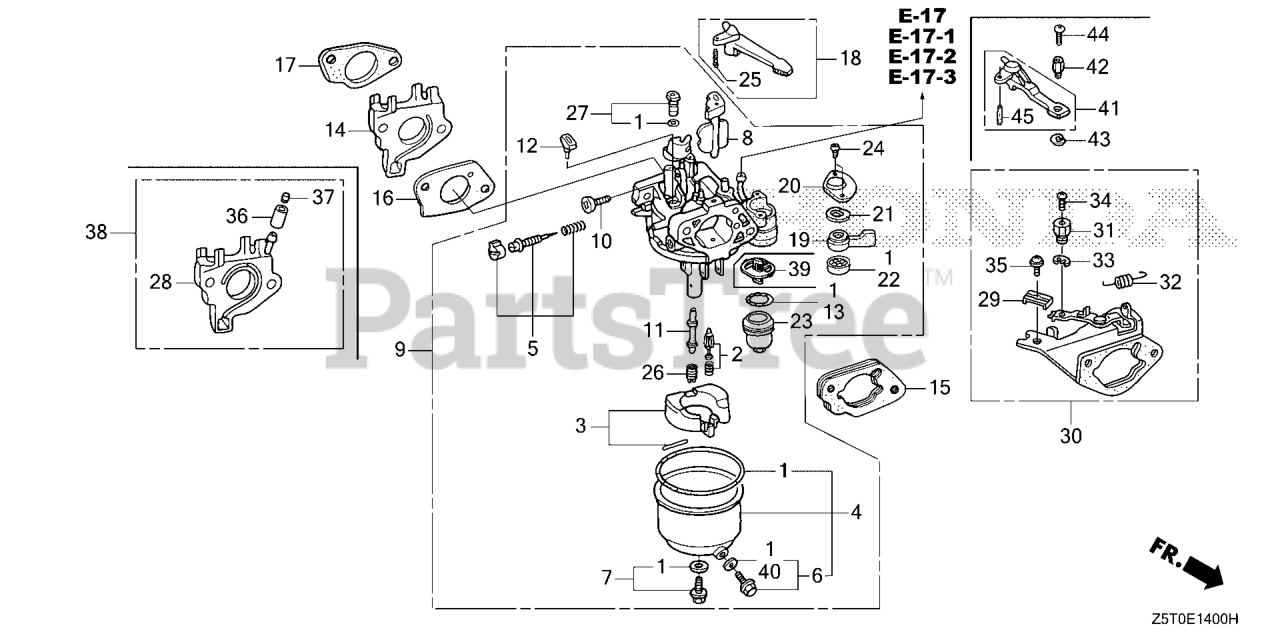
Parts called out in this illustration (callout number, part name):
1	GASKET SET (INCLUDE 16173-001-004) (INCLUDES 16173-001-004)
2	VALVE SET, FLOAT
3	FLOAT SET (CARBURETOR NO.)
4	CHAMBER SET, FLOAT
5	SCREW SET
5	SCREW SET (Honda Code 4219879). (CARBURETOR NO.)
6	SCREW SET, DRAIN
7	SCREW SET (CARBURETOR NO.)
9	CARBURETOR ASSY. (BE88A A)
9	CARBURETOR ASSY. (BEC0A A)
10	SCREW, THROTTLE STOP
11	NOZZLE, MAIN
11	NOZZLE, MAIN (CARBURETOR NO.)
12	COLLAR, SET
13	GASKET, FUEL STRAINER CUP
14	INSULATOR, CARBURETOR
15	SPACER, CARBURETOR
16	GASKET, CARBURETOR
17	GASKET, CARBURETOR INSULATOR
18	LEVER, CHOKE (STD)
19	LEVER, VALVE
20	PLATE, LEVER SETTING (CARBURETOR NO.)
21	SPRING, PETCOCK LEVER (CARBURETOR NO.)
22	GASKET, VALVE
23	CUP, FUEL STRAINER
24	SCREW, PAN (3X6)
25	PIN, SPRING (2X12)
26	JET, MAIN (#98) Use from Engine SN BE87A A to BE87A A.
26	JET, MAIN (#102) (ADVENTURE GREEN) (CARBURETOR NO.)
26	JET, MAIN (#105) Use from Engine SN BE87H A.
26	JET, MAIN (#108) (CARBURETOR NO.)
27	JET SET, PILOT (#38)
27	JET SET, PILOT (#40) (ADVENTURE GREEN) (CARBURETOR NO.)
39	FILTER, CUP (CARBURETOR NO.)
40	WASHER, PLAIN (6.2X10.7 DRAIN) (CARBURETOR NO.)
